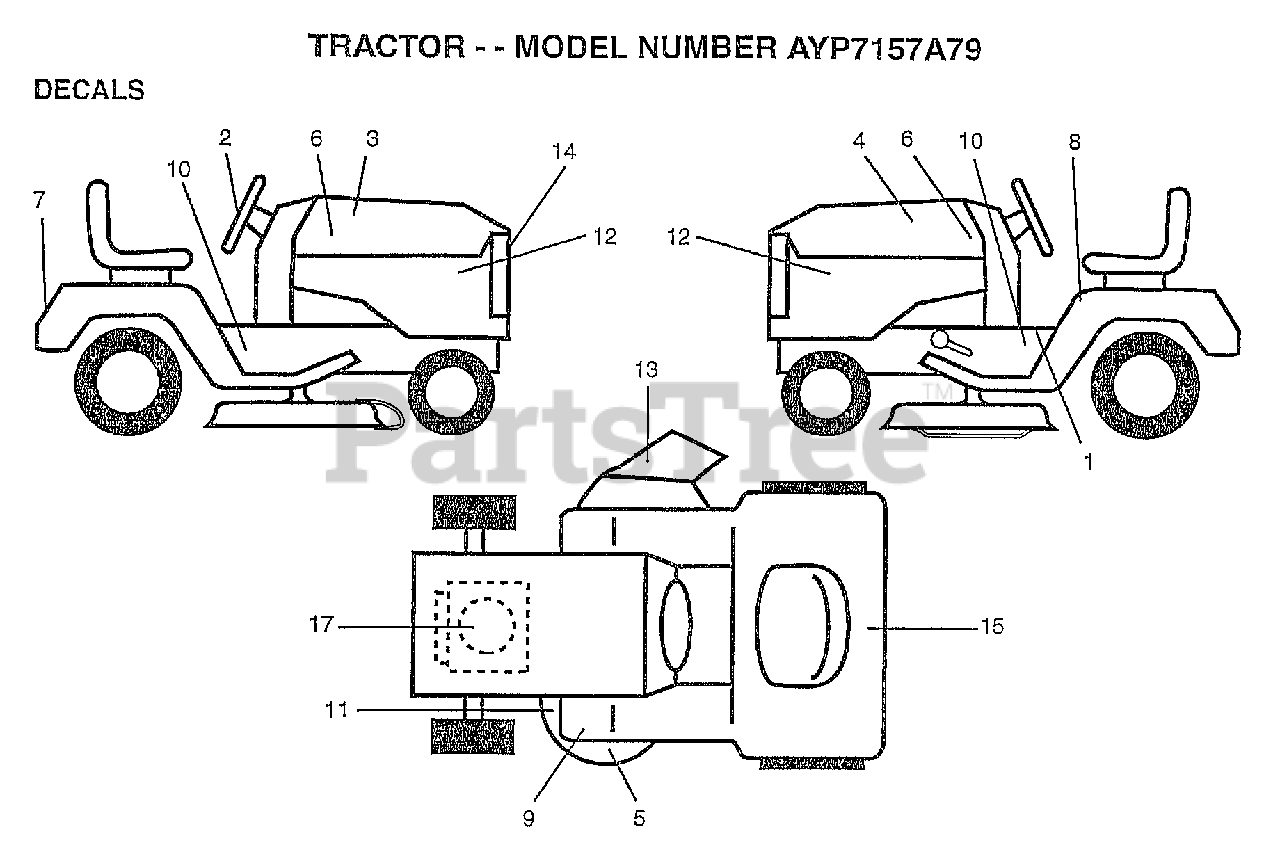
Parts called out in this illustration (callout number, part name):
1	"DECAL DASH,OPER."
2	DECAL STEER WHL
3	DECAL HOOD RH
4	DECAL HOOD LH
5	DECAL DECK WIZ +
6	NAMEPLATE.HD.WIZA
8	"DECAL DANGER,FEND"
10	DECAL CHASSIS WIZ
11	DECAL
12	"DECAL PANEL,SIDE"
13	DECAL DECK MULCH
14	DECAL.LENS.WIZARD
15	DECAL.BATRY.3-3908
17	DECAL, ENGINE
